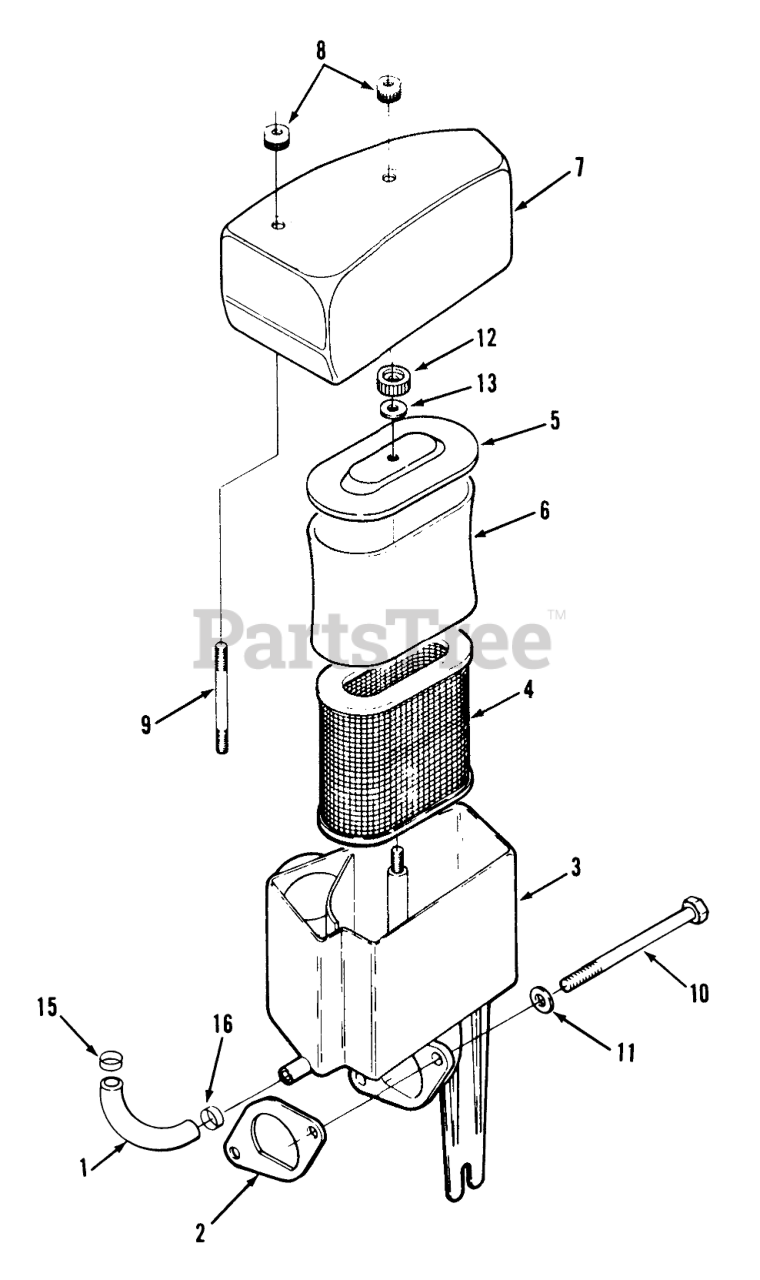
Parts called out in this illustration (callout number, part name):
1	HOSE-BREATHER
2	Gasket
3	Adapter
4	AIR CLEANER ELEMENT
5	COVER-ELEMENT
6	WRAPPER-ELEMENT
7	COVER-AIR CLEANER
8	KNOB M6
10	HHCS-M8 X 100MM
11	Nut-M8
13	GROMMET
15	CLAMP-HOSE
16	CLAMP-HOSE
